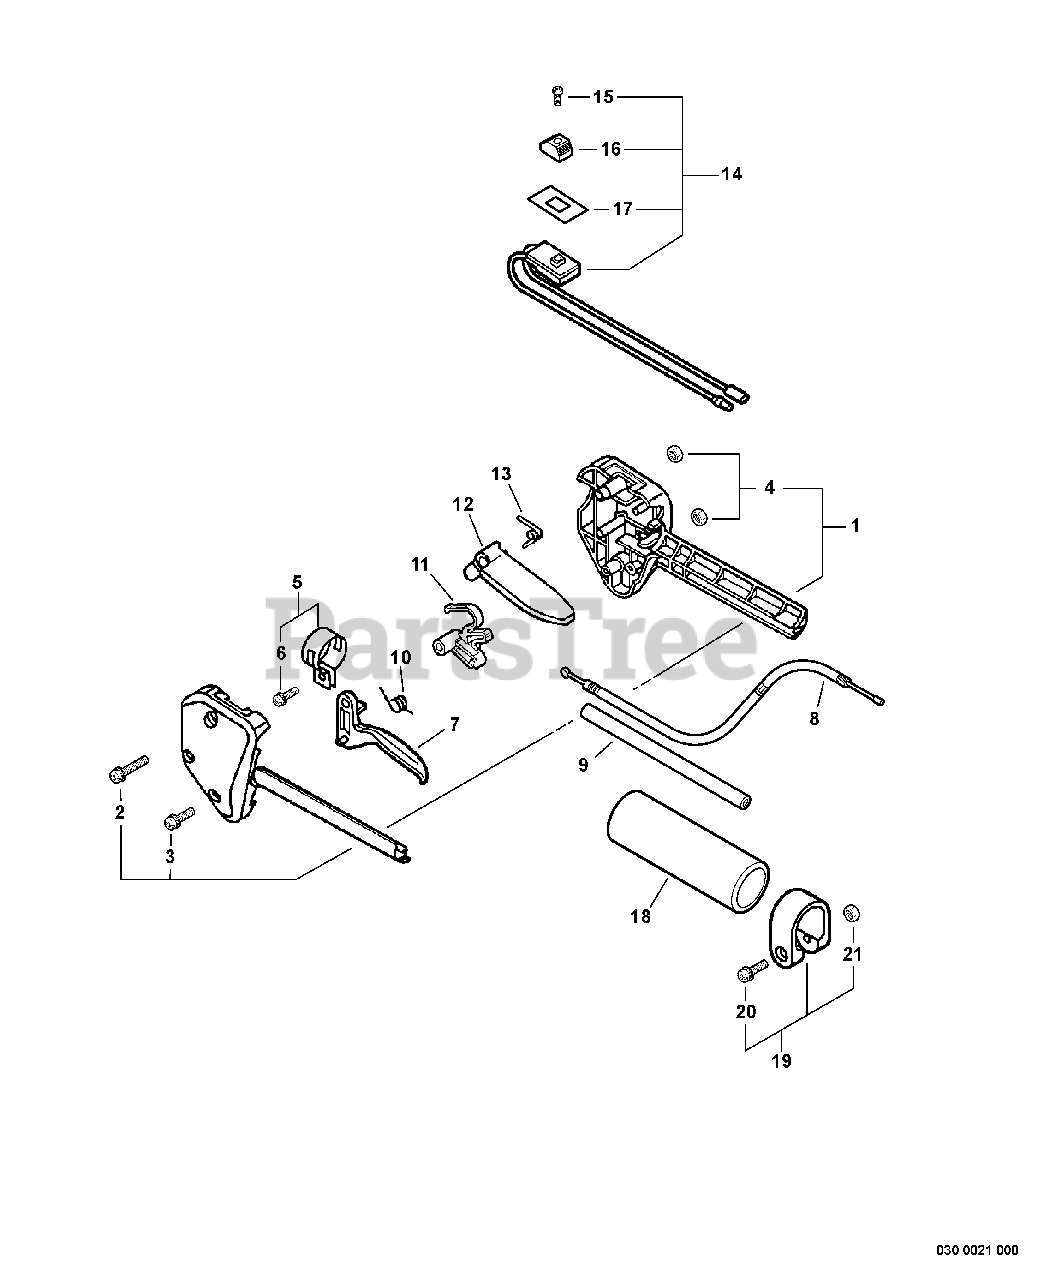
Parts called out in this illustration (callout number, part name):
1	CONTROL HANDLE KIT
2	SCREW - 5X35
3	SCREW - 5X25
5	CLAMP KIT
6	SCREW - 5X14
7	TRIGGER, THROTTLE
8	CABLE, THROTTLE
9	TUBE - VINYL
10	SPRING, TRIGGER
11	LOCKOUT, THROTTLE
12	LEVER, TRIGGER LOCKOUT
13	SPRING, LOCKOUT LEVER
14	IGNITION SWITCH ASSY
15	SCREW - 3X10
16	KNOB, SWITCH - ORANGE
17	COVER, SWITCH - STOP
18	GRIP, HANDLE
19	CLAMP KIT
20	SCREW - 5X28
